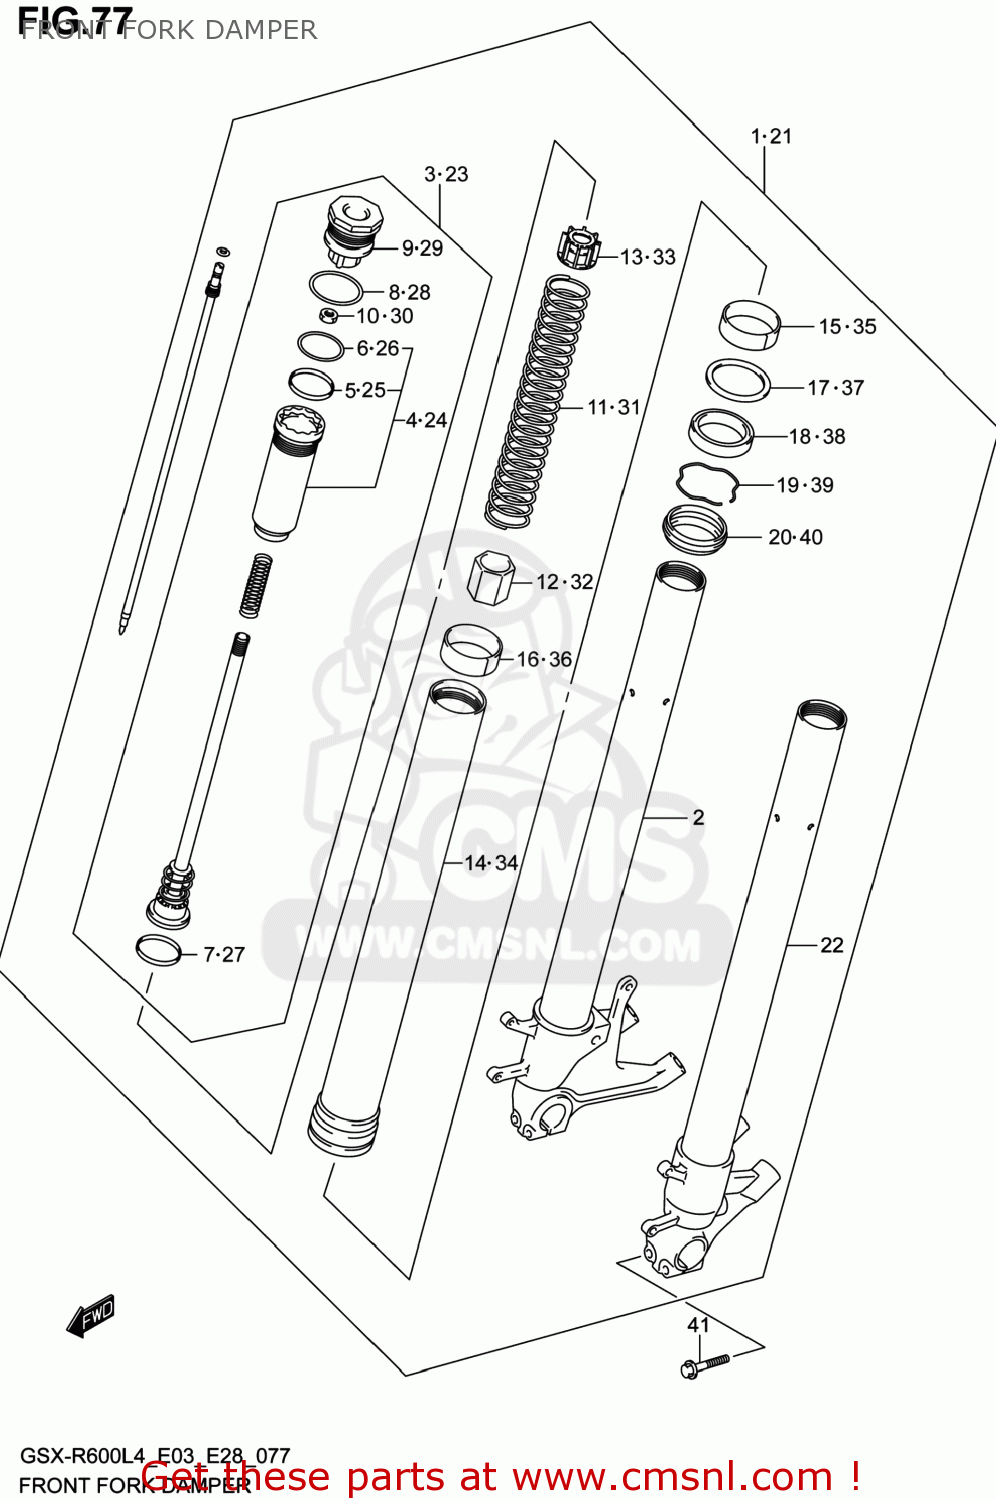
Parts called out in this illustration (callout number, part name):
1	DAMPER ASSY,FR FORK,R
2	TUBE,INNER,R
3	ROD,PISTON
4	CASE,ROD GUIDE
5	PISTON RING
6	O RING
7	RING,PISTON
8	O RING,FORK BOLT
9	BOLT
10	NUT
11	SPRING
12	COLLAR,SPRING
13	COLLAR,SPRING
14	TUBE,OUTER
15	BUSH,GUIDE
16	BUSH,SLIDE
17	SPACER,SEAL
18	SEAL,OIL
19	CIRCLIP,FORK OIL SEAL
20	SEAL,DUST
21	DAMPER ASSY,FR FORK,L
22	TUBE,INNER,L
23	ROD,PISTON
24	CASE,ROD GUIDE
25	PISTON RING
26	O RING
27	RING,PISTON
28	O RING,FORK BOLT
29	BOLT
30	NUT
31	SPRING
32	COLLAR,SPRING
33	COLLAR,SPRING
34	TUBE,OUTER
35	BUSH,GUIDE
36	BUSH,SLIDE
37	SPACER,SEAL
38	SEAL,OIL
39	CIRCLIP,FORK OIL SEAL
40	SEAL,DUST
41	BOLT
